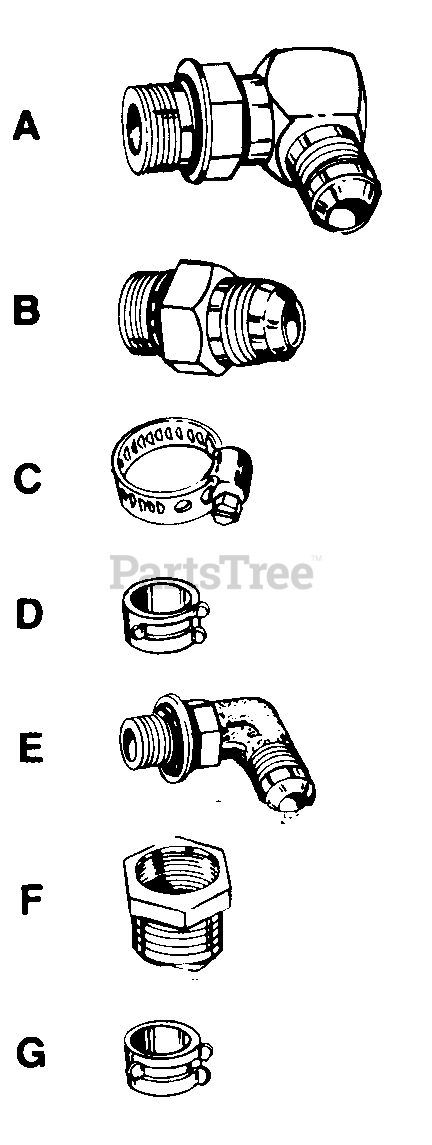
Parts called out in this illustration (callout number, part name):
A	7/8-14 SAE Boss to 3/4-16 JIC.
B	Adapter-"O"-Ring, Boss to Male JIC.
C	Hose Clamp .406 Dia. for Ref. No. 9
D	Hose Clamp 3/8" Dia.
E	1/2-20 SAE Boss to 1/2-20 JIC.
F	Pipe Reducer 1/2-14 to 3/8-18 NPT
G	Hose Clamp .37 Dia. Finish-Green Paint
